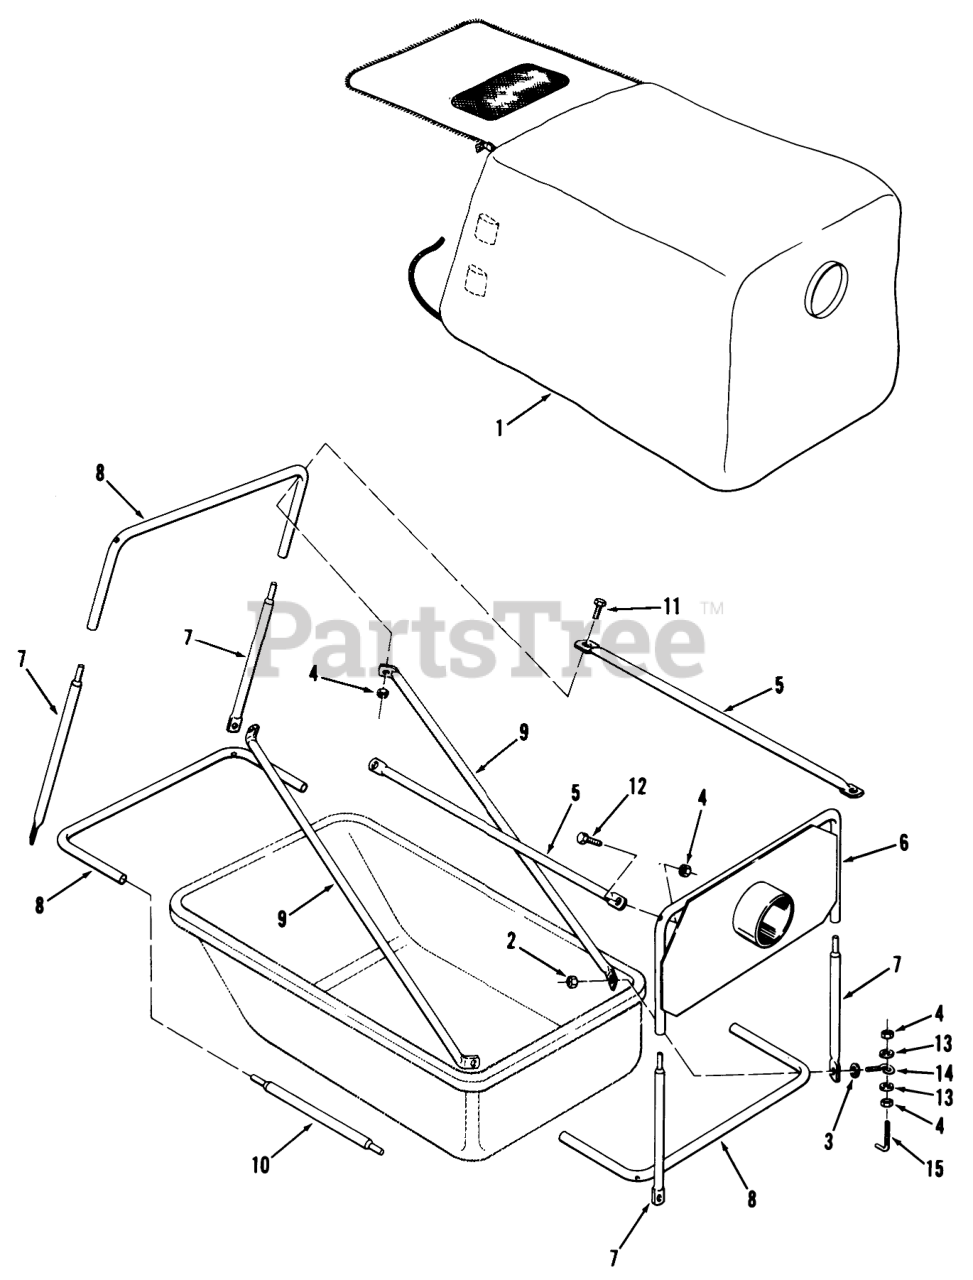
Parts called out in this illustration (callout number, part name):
1	Cart Cover
2	Nut
4	Nut
5	Top Tube
6	Front Hose Adapter
7	Upright Brace
8	U-Tube
9	Cross Tube
10	Side Tube
11	Bolt
12	Bolt
13	WASHER 5/16 SAE
14	EYE BOLT
15	J-Bolt
